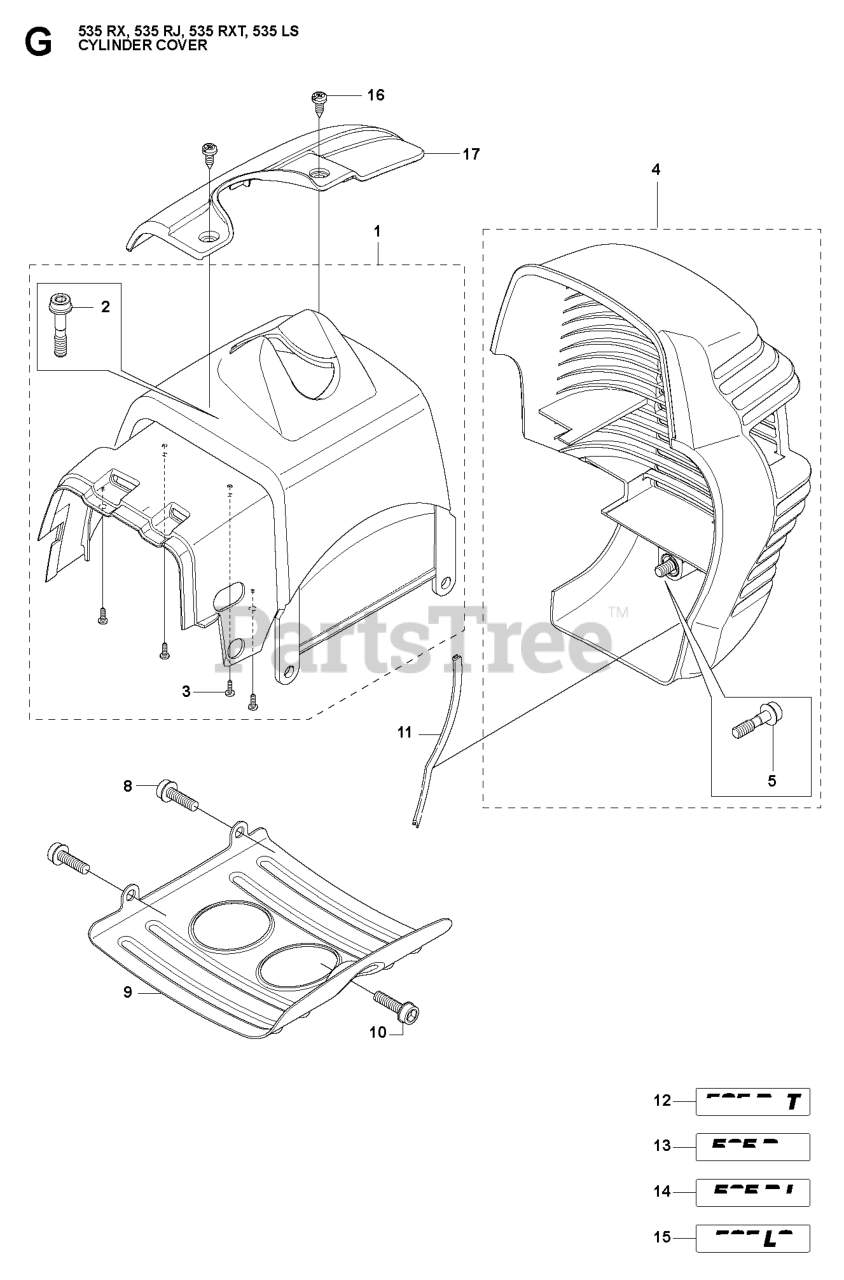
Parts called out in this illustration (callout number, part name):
1	CYLINDER COVER
2	SCREW IHSCFMO
4	HEAT PROTECTOR
5	SCREW IHSCFMO
12	LABEL CYLINDER COVER 535 RXT
13	LABEL CYLINDER COVER 535 RX
14	LABEL CYLINDER COVER 535 RJ
16	SCREW CCRPANT ST4.2X9.5 DS
17	ARM PROTECTION
